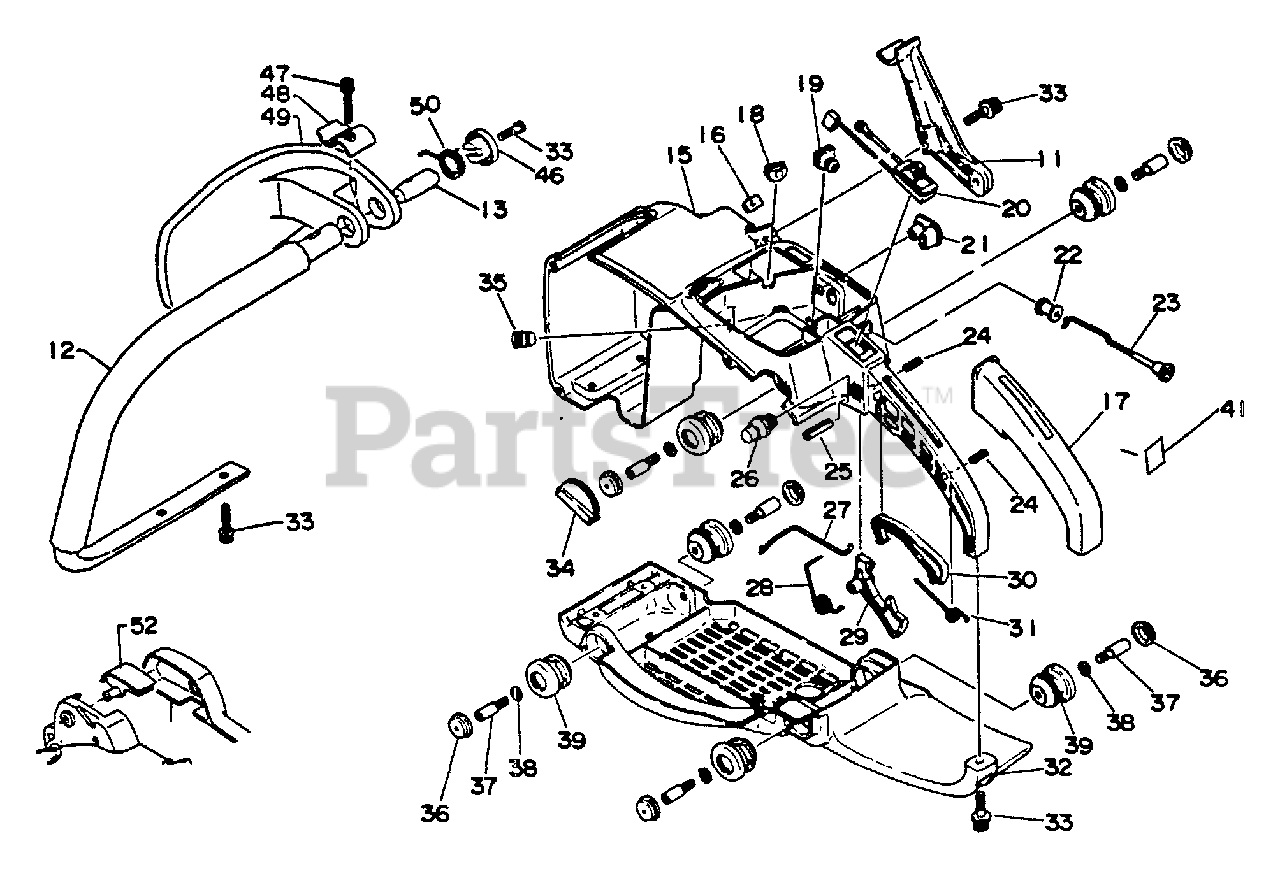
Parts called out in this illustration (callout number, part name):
11	BRACKET, HANDLE - UPPER
12	HANDLE - FRONT
15	HANDLE - REAR
17	GRIP, HANDLE - REAR
20	IGNITION SWITCH ASSY
21	GROMMET
23	ROD, CHOKE
24	PIN - SPRING -- 4X13
25	PIN - SPRING -- 5X25
26	LATCH, THROTTLE
27	ROD, THROTTLE
28	SPRING, TRIGGER
29	TRIGGER, THROTTLE
30	LOCKOUT, THROTTLE
31	SPRING, LOCKOUT LEVER
32	SUPPORT
33	SCREW - 5X20
34	COVER, CUSHION
36	CAP, CUSHION
38	LOCKWASHER - 5
41	LABEL - CHOKE
46	RETAINER
47	SCREW - 5X35
49	GUARD
52	COVER
